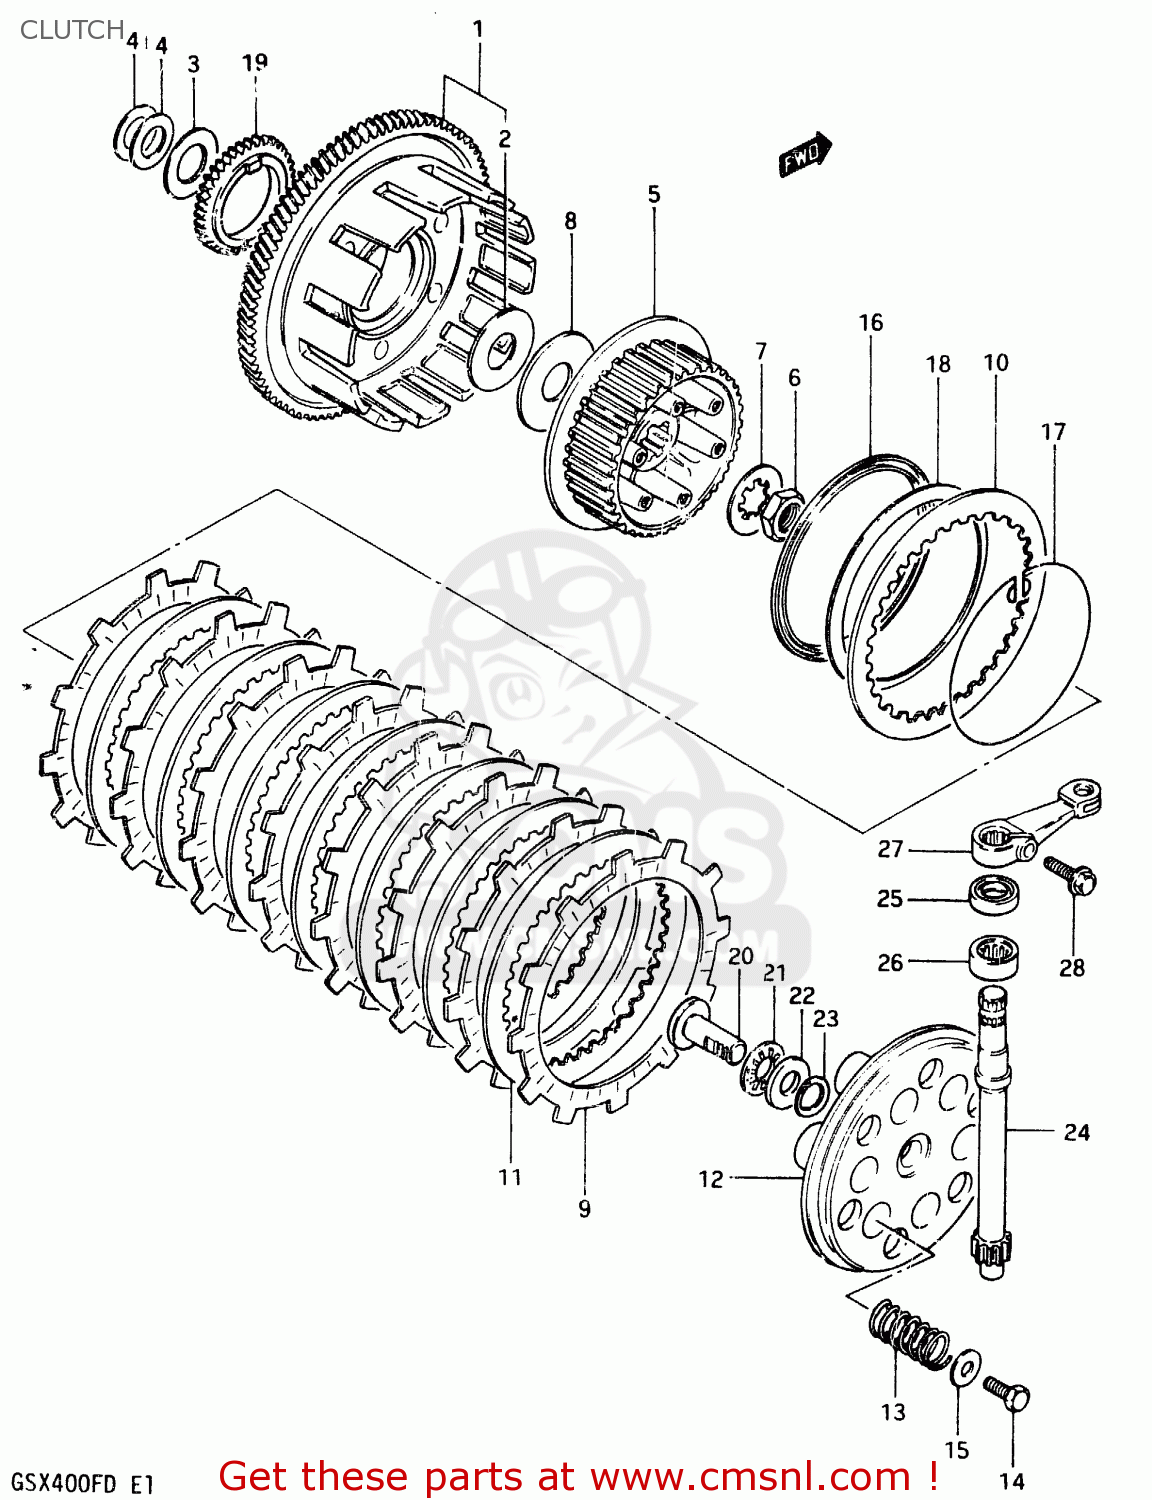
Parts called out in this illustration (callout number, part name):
1	GEAR SET, PRIMARY DRIVEN (NT:92)
2	SHIM (T:1.00)
3	WASHER
4	WASHER
5	HUB, SLEEVE
6	NUT
7	WASHER,LOCK
8	WASHER
9	PLATE,CLUTCH DRIVE (MCA)
10	PLATE,CLUTCH DRIVEN(T:2.0) (NAS)
11	PLATE,CLUTCH DRIVEN (NAS)
12	DISC, PRESSURE
13	SPRING
14	BOLT, UPPER
15	WASHER
16	SEAT,WAVE WASHER
17	RING,STOPPER
18	WASHER
19	GEAR, OIL PUMP DRIVE (NT:38)
20	RACK,CLUTCH RELEASE
21	BEARING(15X28X2)
22	WASHER
23	WASHER
24	PINION, RELEASE
25	OIL SEAL
26	BEARING(15X22X12)
27	ARM,CLUTCH RELEASE
28	BOLT,REAR
